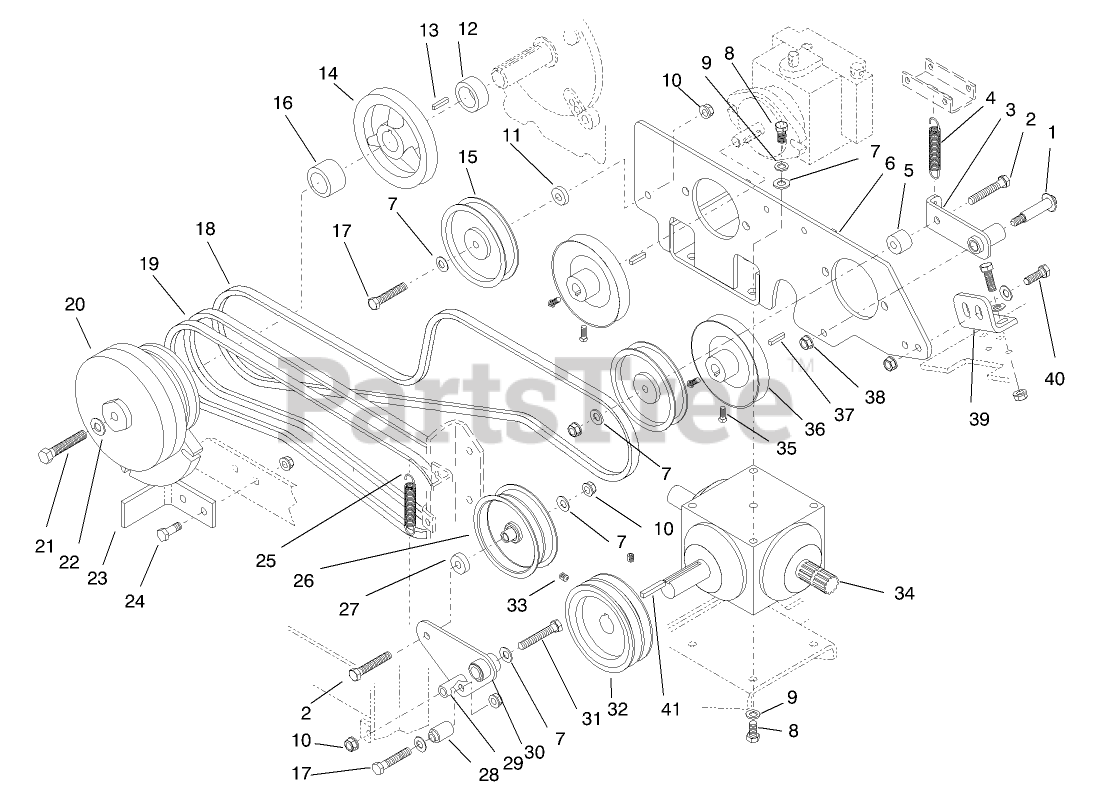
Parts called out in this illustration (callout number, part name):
1	BOLT-WHEEL
2	SCREW-HH
3	IDLER ARM ASM
4	SPRING-EXTENSION
5	SPACER-ARM, IDLER
6	PUMP MOUNT ASM
7	WASHER-FLAT
8	SCREW-HHF
10	NUT-LOCK, NI
11	Washer
12	SPACER-SHAFT, ENGINE
14	PULLEY-ENGINE
15	PULLEY-IDLER
16	SPACER-SHAFT, ENGINE
17	SCREW-HH
18	V-BELT
19	BELT - PTO (SET)
20	Clutch ASM
21	SCREW-HH
22	WASHER-FLAT
23	STOP-CLUTCH
24	SCREW-HH
25	SPRING-EXTENSION
26	PULLEY-IDLER
27	SPACER-IDLER
28	SPACER - SPRING
29	SPACER
30	IDLER ARM ASM
31	Screw-Hhcs
32	PULLEY-CLUTCH
33	SCREW-HSH
34	Gearbox-PTO Drive
35	SCREW-SET
36	PULLEY-PUMP, TRACTION
37	KEY-PUMP
38	NUT-LOCK
39	MOUNT-PLATE, PUMP
40	SCREW-HHF
41	KEY-SQUARE
42	SHAFT-DRIVE
43	SCREW-HH
44	PIN-SPRING
